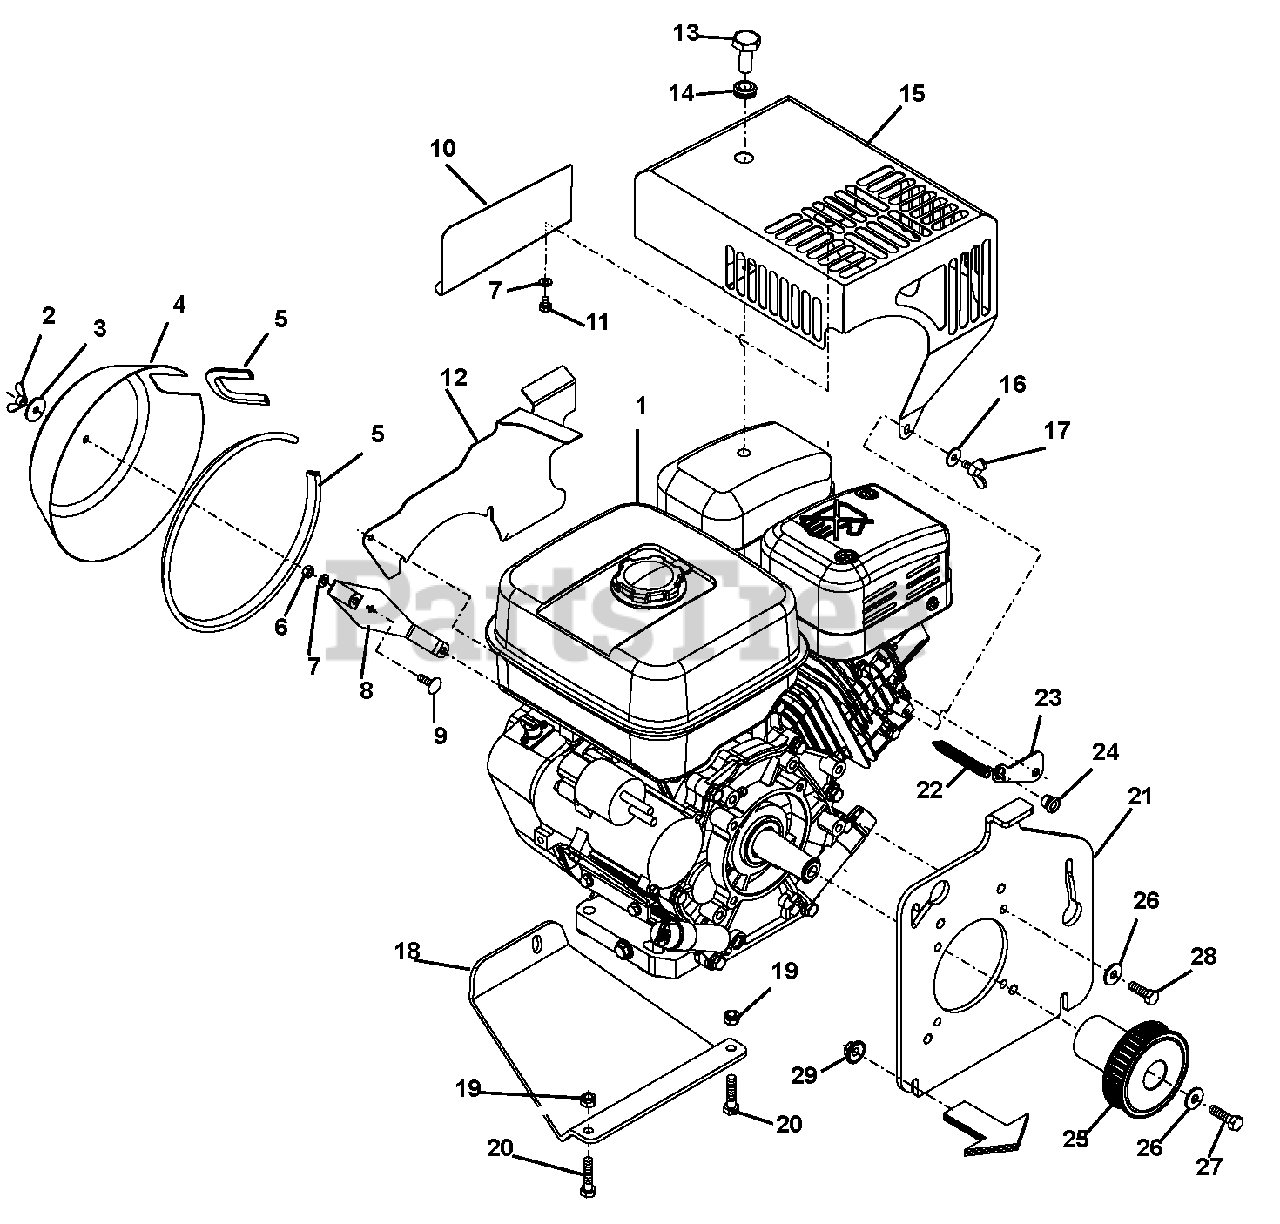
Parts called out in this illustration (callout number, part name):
1	Engine 9 HP EST, Robin, EST
2	Nut, Wing
3	Washer, 7 x 25 x 1.8
4	Bonnet
5	Edge Protection, N802 6,5 x 8
6	Nut, Hex D934 M6
7	Washer, M6
9	Screw, BN289 M6 x 20
10	Sheet, Divider
11	Screw, D912 M6 x 35
12	Winter Plating
13	Wing Nut
15	Guard, Sheet Metal
16	Washer, M6
17	Wing Screw, D316 M6 x 12
18	Guard, Sheet Metal
19	Nut, Lock D985 M8
20	Bolt, Hex D933 M8 x 35
21	Retaining Plate
22	Tension Spring
24	Bushing
25	Pulley
26	Washer, M8
27	Bolt, Hex D933 M8 x 30
28	Bolt, Hex UNF 5/16" x 1"
29	Lock Nut, M8
